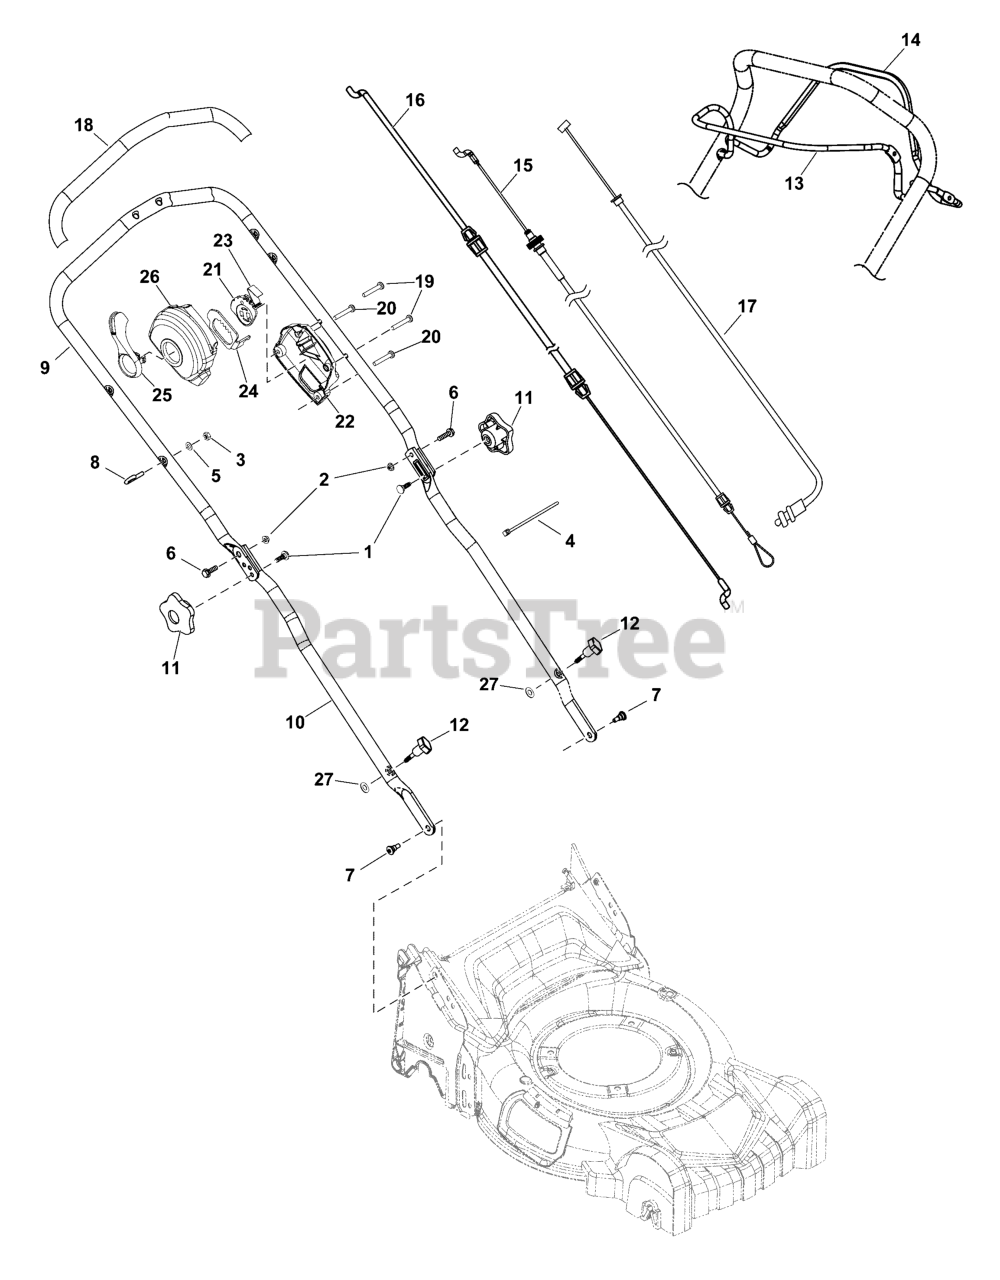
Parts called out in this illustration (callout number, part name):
1	BOLT, 5/16-18 x 1 G5
2	NUT, Flange Nylock , 1/4-20
3	NUT, Nylock, M6-1.0
4	CABLE CLIP
5	WASHER, A6.4
6	SCREW, 1/4-20
7	BOLT, Shoulder
8	BOLT, Eye
9	HANDLE, Upper
10	HANDLE, Lower
11	WING KNOB, 5/16-18
12	WING KNOB
13	BAIL, Control, Red
14	BAIL, Drive
15	CABLE, Drive
16	CABLE, Control
17	CABLE, Speed Select
19	SCREW, 184-15 x 1-1/2
20	SCREW, 184-15 x 3/4
21	SPEED ACTUATOR
22	HOUSING, Lower
23	SHIFT SPRING
24	RACK PLATE
25	LEVER, Speed Select
26	HOUSING, Upper
27	WASHER, 1/4 x 17/32
